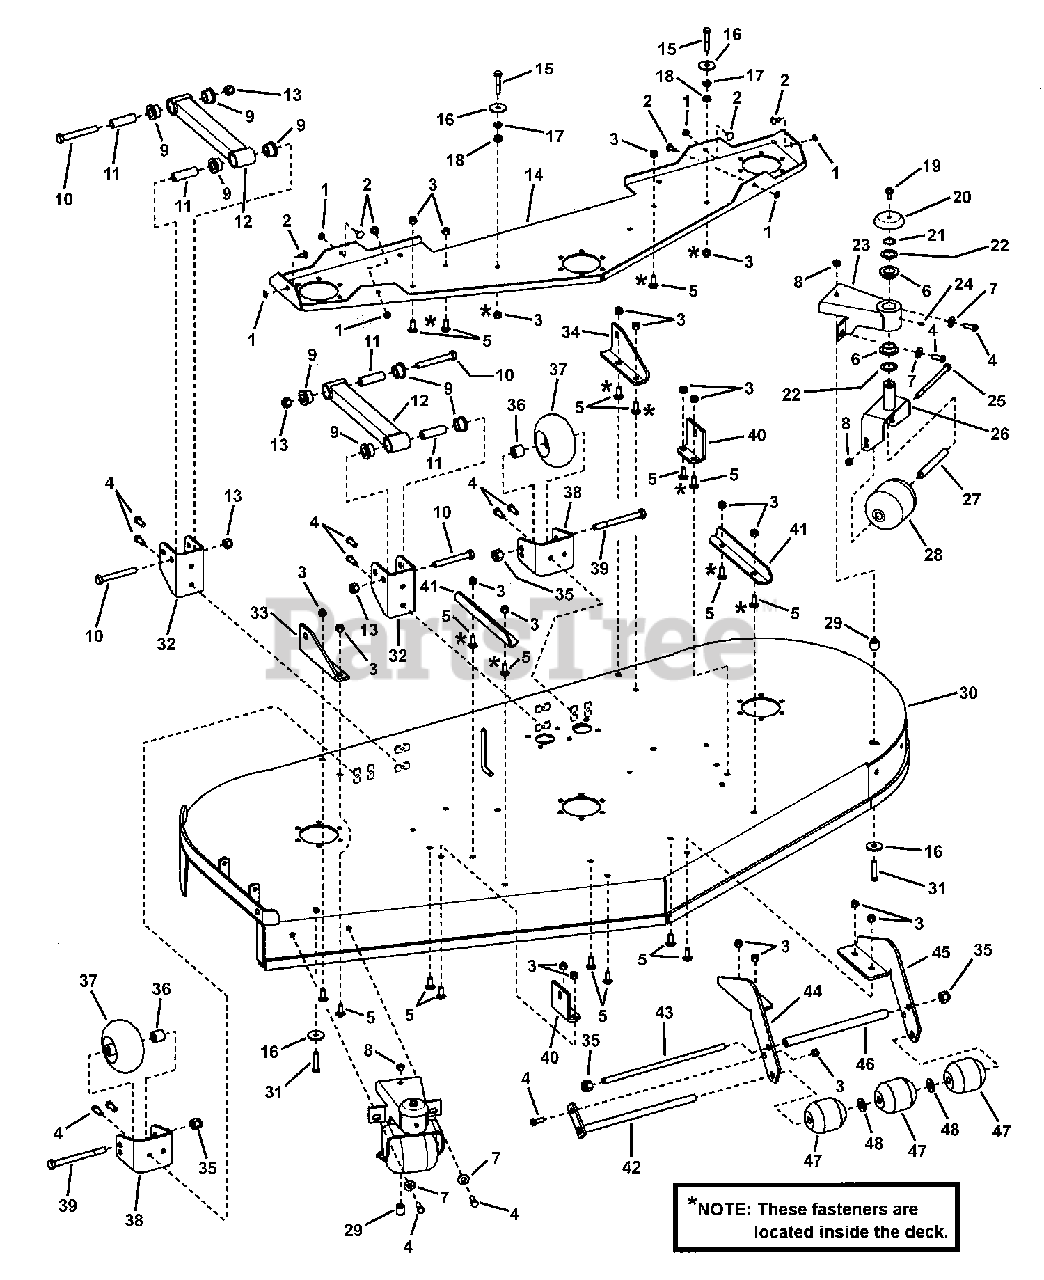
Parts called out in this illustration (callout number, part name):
1	BOLT RETAINER, 5/16" Bolt
2	BOLT, 5/16-18 x 5/8" Short Neck Carriage, GR 5
3	NUT, 3/8-16 HEX NYLON LOCK
4	BOLT, 3/8-16 X 1" GD5 CZ
5	BOLT, 3/8-16 x 1" Square Neck Carriage, GR 5
6	BUSHING, Idler (Powdered Metal)
7	WASHER, 3/8" USS
8	NUT, 3/8-16 Hex Center Lock
9	BUSHING- Suspension
10	BOLT, 1/2-13 x 3-3/4" Hex Head Cap
11	SLEEVE, Suspension
12	WELDMENT, Pusher Bar
13	NUT, 1/2-13 HEX NYLON LOCK
14	73" DECK STIFFENER
15	BOLT, 3/8-16 X 2, GD5, CZ
16	WASHER, .406 x 1.50 x .120 Flat
17	BUSHING, 3/8" Plastic
18	NUT, 3/8-16 HEX SERRATED FLANGE
19	SCREW, 5/16-18 x 3/4" Hex Washer Self-Tap
20	CAP, Caster Shaft
21	RING, 1" External Retaining
22	BUSHING, 1" Machine
23	WELDMENT, Gauge Wheel Support
24	LUBE FITTING, 3/16"
25	BOLT, 3/8-16 X 6" GD5 CZ
26	WELDMENT, Caster, Gauge Wheel
27	TUBE, Axle
28	ROLLER 3-3/4 Dia. x 4-13/16" long
29	SPACER, 3/4 O.D. x 13/32 I. D. x 3/4" long
30	WELDMENT, 73" DECK
31	SCREW, 3/8-16 x 1-3/4" Hex Head Cap, GR 5
32	BRACKET, Stabilizer
33	BRACKET, Deck Lift, RH Rear
34	BRACKET, Deck Lift, LH Rear
35	NUT, 1/2-13 Hex Nyloc
36	SPACER, Gauge Wheel
37	GAUGE WHEEL, Polyethylene
38	BRACKET, Gauge Wheel
39	BOLT, 1/2-13 X 5 GD5 YZ
40	DECK LIFT BRACKET, Front
41	ANGLE, Deck Stiffener, 73 Deck
42	WELDMENT, Pivot Pin
43	ROD, Roller (1/2-13 Threaded)
44	BRACKET, Front Roller, RH
45	BRACKET, Front Roller, LH
46	TUBE, Roller
47	ROLLER, Low Density Polyethylene
48	WASHER, 5/8" Flat SAE
